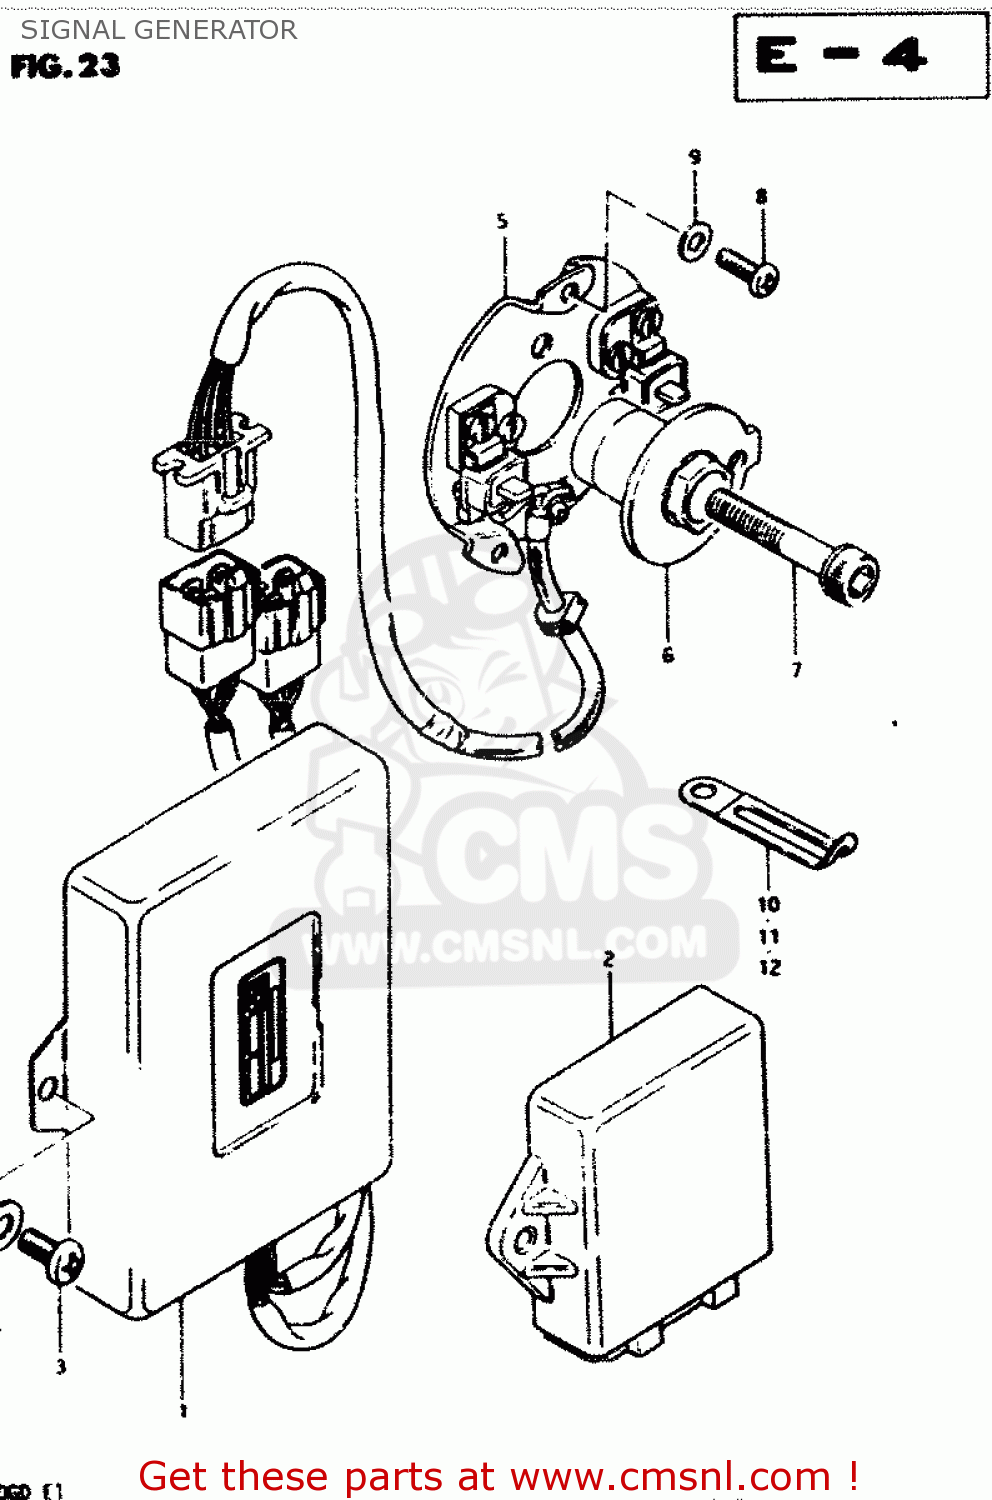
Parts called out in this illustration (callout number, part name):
1	IGNITER UNIT ASSEMBLY
2	IGNITOR UNIT,ESA
3	SCREW 6X12
4	WASHER
5	STATOR,SIGNAL GENERATOR
6	GOVERNOR ASSEMBLY
7	BOLT
8	SCREW(5X12)
9	WASHER
10	CLAMP L:35
11	CLAMP
12	CLAMP
